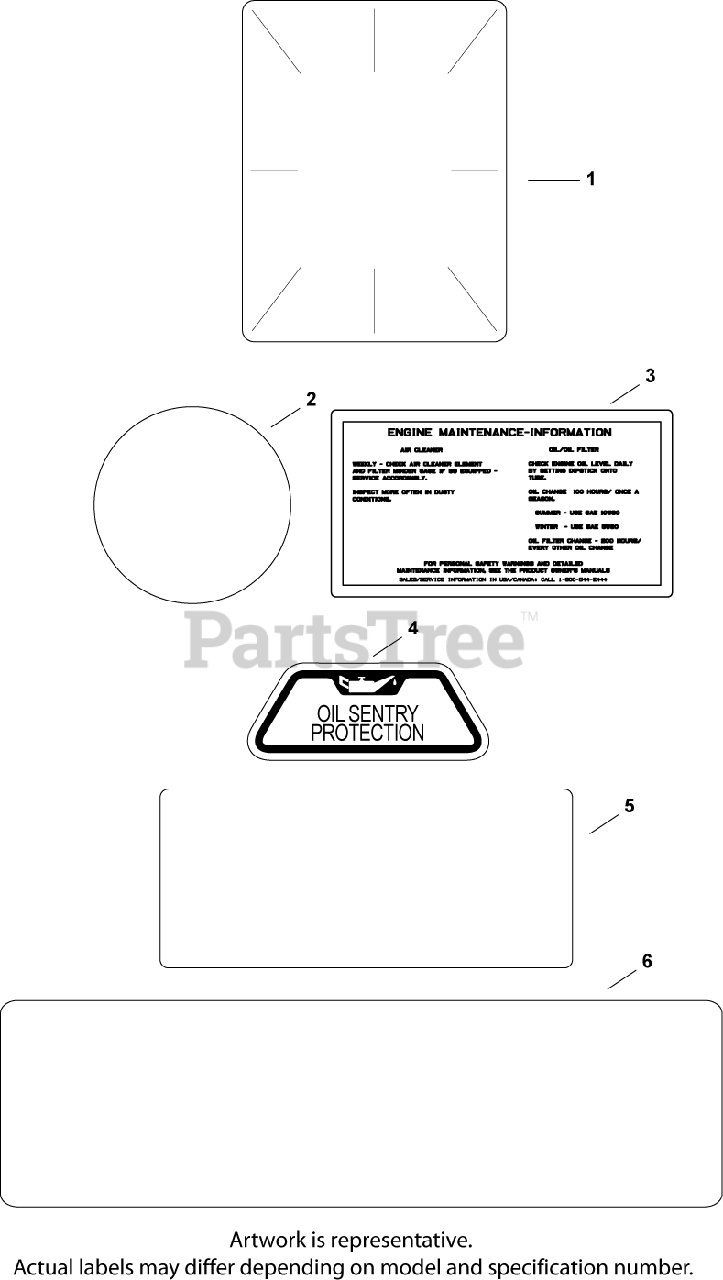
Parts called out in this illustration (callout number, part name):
1	DECAL, CLEAR LAMINATE USE 25 113 70-S
2	DECAL, GRASS SCREEN USE 24 113 499-S
3	DECAL, AIR CLEANER - (#DSC)
4	DECAL, OIL SENTRY - (#DSC)
5	DECAL, REPL ENGINE(NONCERT)
6	DECAL, 25 HP - DISCONTINUED
